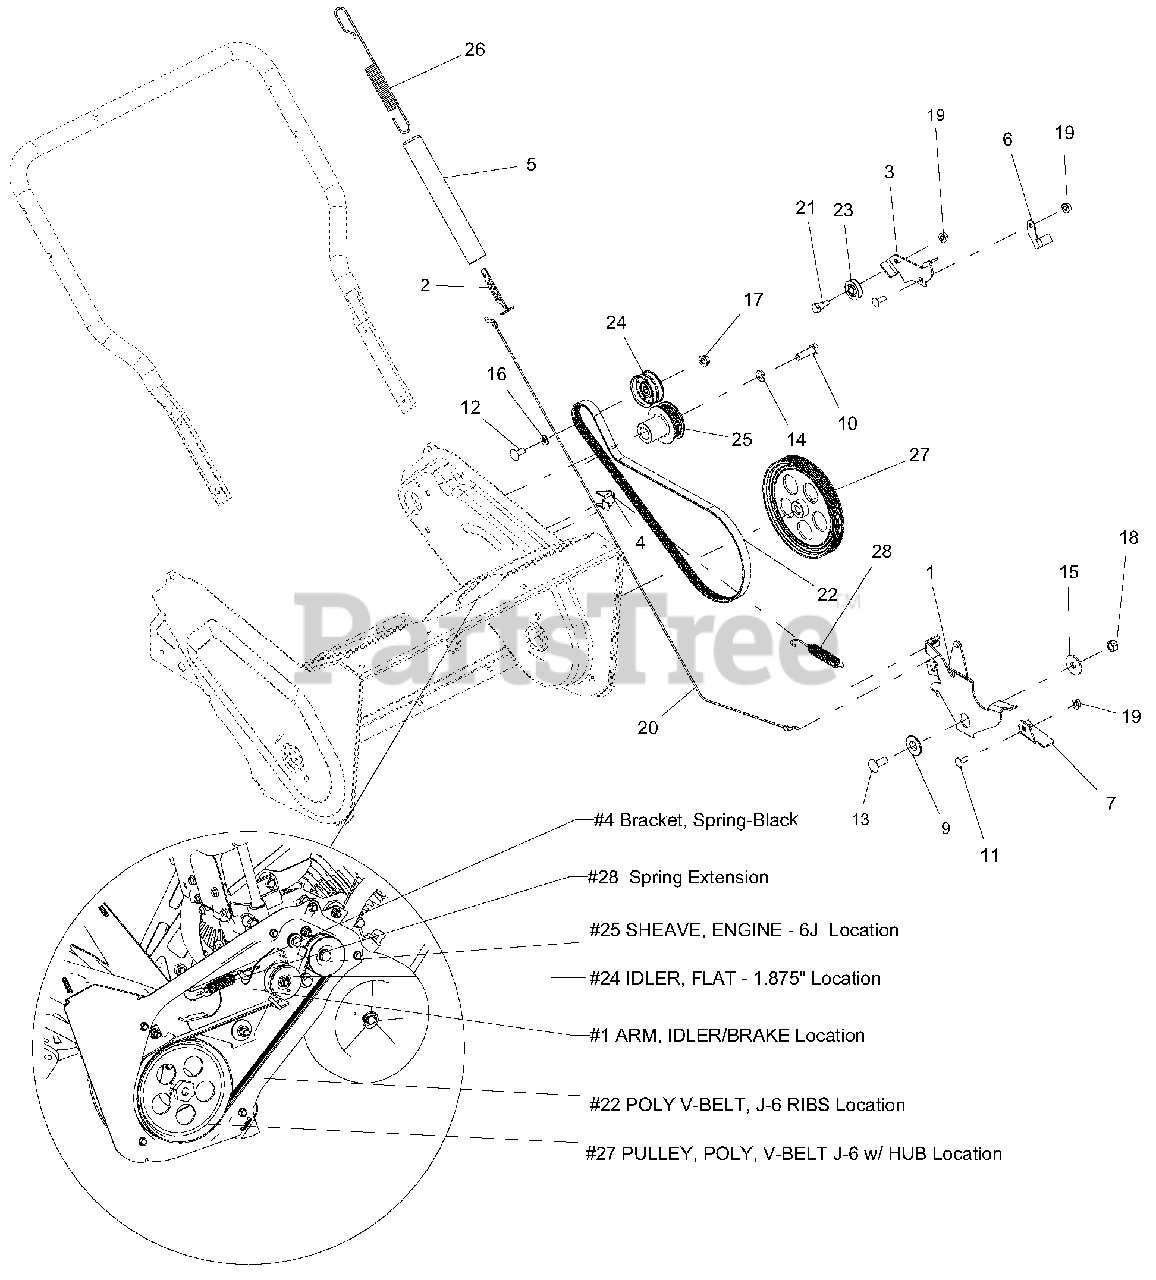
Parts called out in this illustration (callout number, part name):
1	ARM, IDLER/BRAKE
2	PLATE, CABLE ADJUSTMENT
3	BRKT, CABLE PULLEY
4	BRKT, SPRG
5	COVER, CABLE SPRING
6	FINGER, BELT
7	FINGER, BELT
9	BSHG-FLG .555X.860X.220X1.250
10	BLT-HEX .375-24X1.25 GR5 YWZC
11	@BLT-RDHDSQNK .25-20X.75 G5YZ
12	@BLT-RHDSSQNK .31-18X.75 G5YZ
13	@BLT-RDHDSQNK .38-16X1.00 G5YZ
14	@WSHR-LK .38X.094 REG YWZC
15	@WSHR-FL-STL .406X1.25X.10 ZC
16	WSHR-FL-STL .323X.625X.062 YWZ
17	@NUT-LK-CTR-FLG .31-18 YZ GR F
18	@NUT-LK-CTR .38-16 YWZC
19	@NUT-LK-TOP-FLG .25-20 YWZC
20	CABLE, AUGER
21	BOLT, SHLDR-.375X.375X.25-20
22	POLY V-BELT, J-6 RIBS
23	PULLEY, CABLE
24	IDLER, FLAT - 1.875"
25	SHEAVE, ENGINE - 6J
26	SPRG, EXT .100X.740X8.175
27	PULLEY, POLY V-BELT J-6 W/HUB
28	SPRING, EXTENSION-SWIVEL
